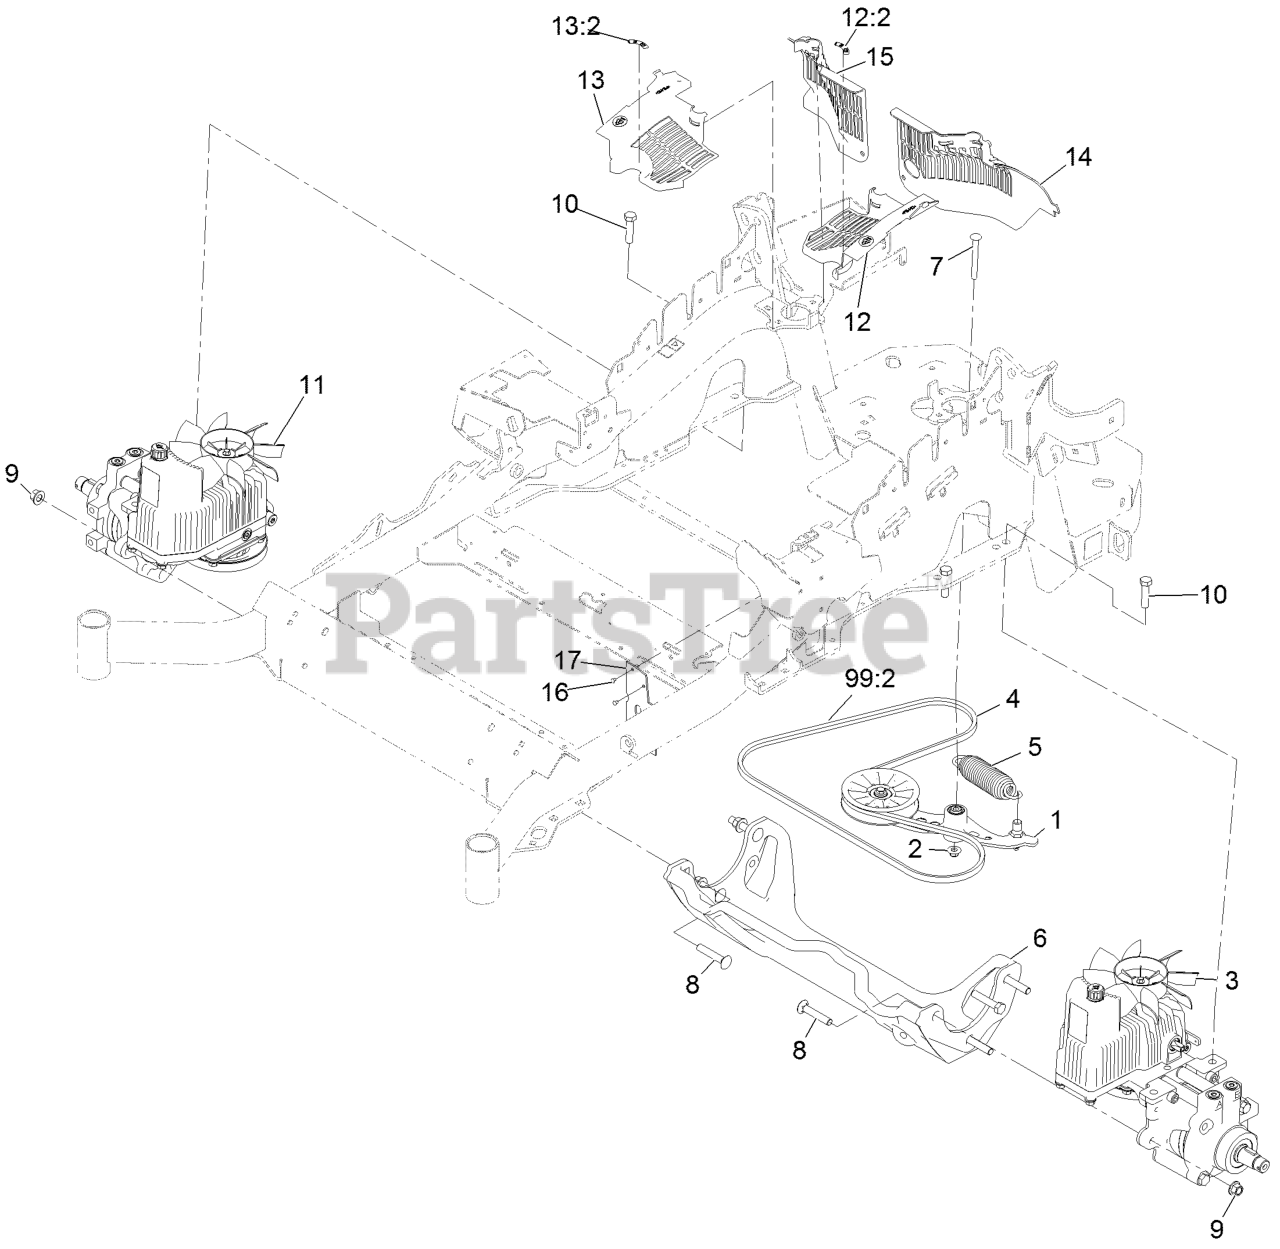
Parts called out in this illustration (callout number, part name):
1	PUMP IDLER ASM
2	Nut-Nyloc 3/8-16 Flg
3	LH HYDRO ASM (12CC W/ SHO
4	BELT
5	SPRING-EXTENSION
6	CRADLE-HYDRO
7	BOLT-SHOULDER, CARRIAGE 3/8-16 X 3 1/2
8	SCREW-CARR
9	Nut-Lock 1/2-13
10	SCREW-HH
11	RH HYDRO ASM (12CC W/ SHO
12	LH HYDRO GUARD ASM
12:2	DECAL-OIL, HYDRO
13	RH HYDRO GUARD ASM
13:2	DECAL-OIL, HYDRO
14	GUARD-HYDRO, REAR (LH)
15	GUARD-HYDRO, REAR (RH)
16	RIVET-POP
17	DEFLECTOR-AIR FLOW
99:2	BELT
